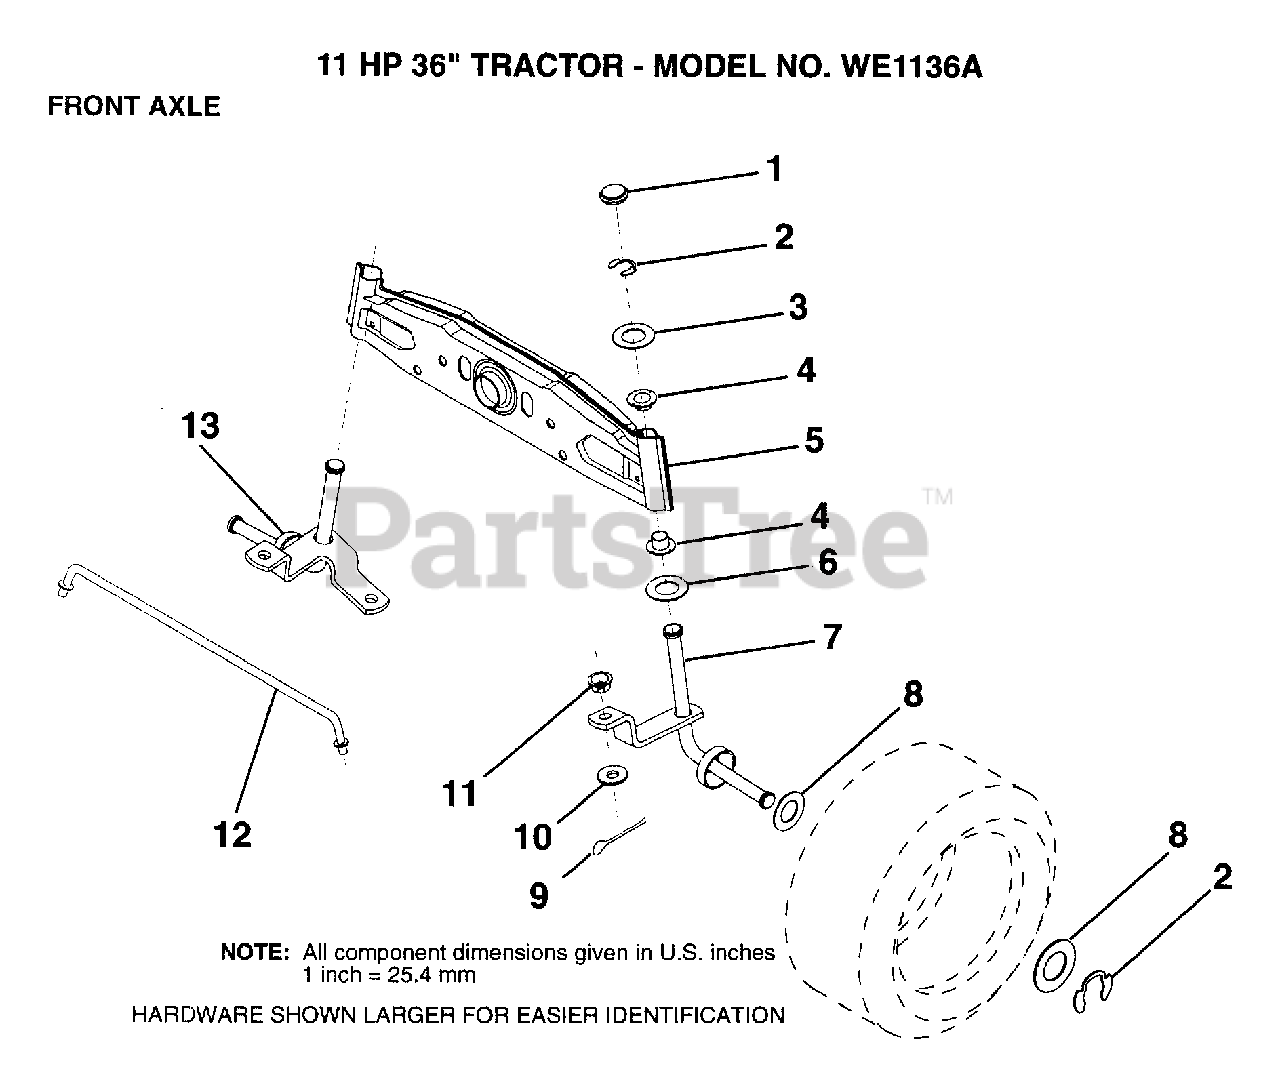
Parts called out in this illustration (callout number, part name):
1	CAP
2	RING
3	WASHER
4	NYLINER
5	AXLE FRONT
6	WASHER .T
7	SPINDLE RH
8	WASHER
9	COTTER PIN
10	WASHER
11	BUSHING.DRAGLINK
12	ROD TIE
13	SPINDLE LH
